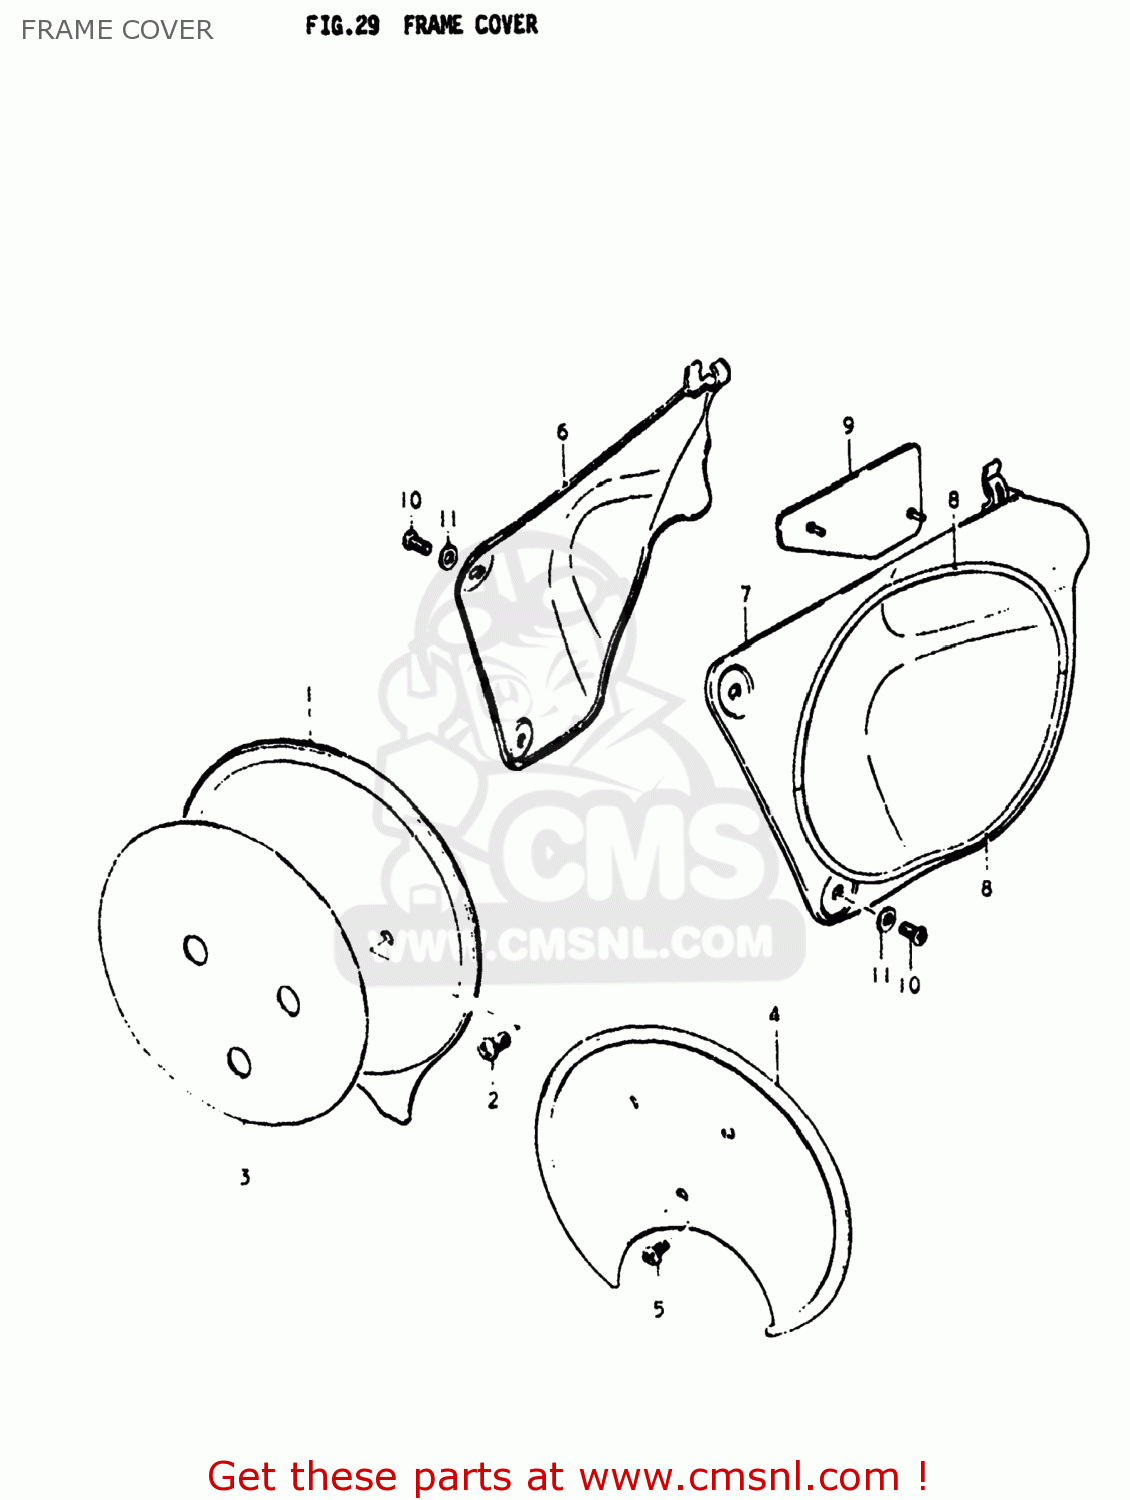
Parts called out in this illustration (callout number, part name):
1	PLATE,NUMBER,FRONT
2	SCREW
3	EMBLEM,FRONT NUMBER PLATE
4	PLATE,FRONT NUMBER
5	SCREW
6	COVER,FRAME,RIGHT
7	COVER,FRAME,LEFT
8	TAPE,FRAME COVER
10	SCREW 6X12
11	SPACER
